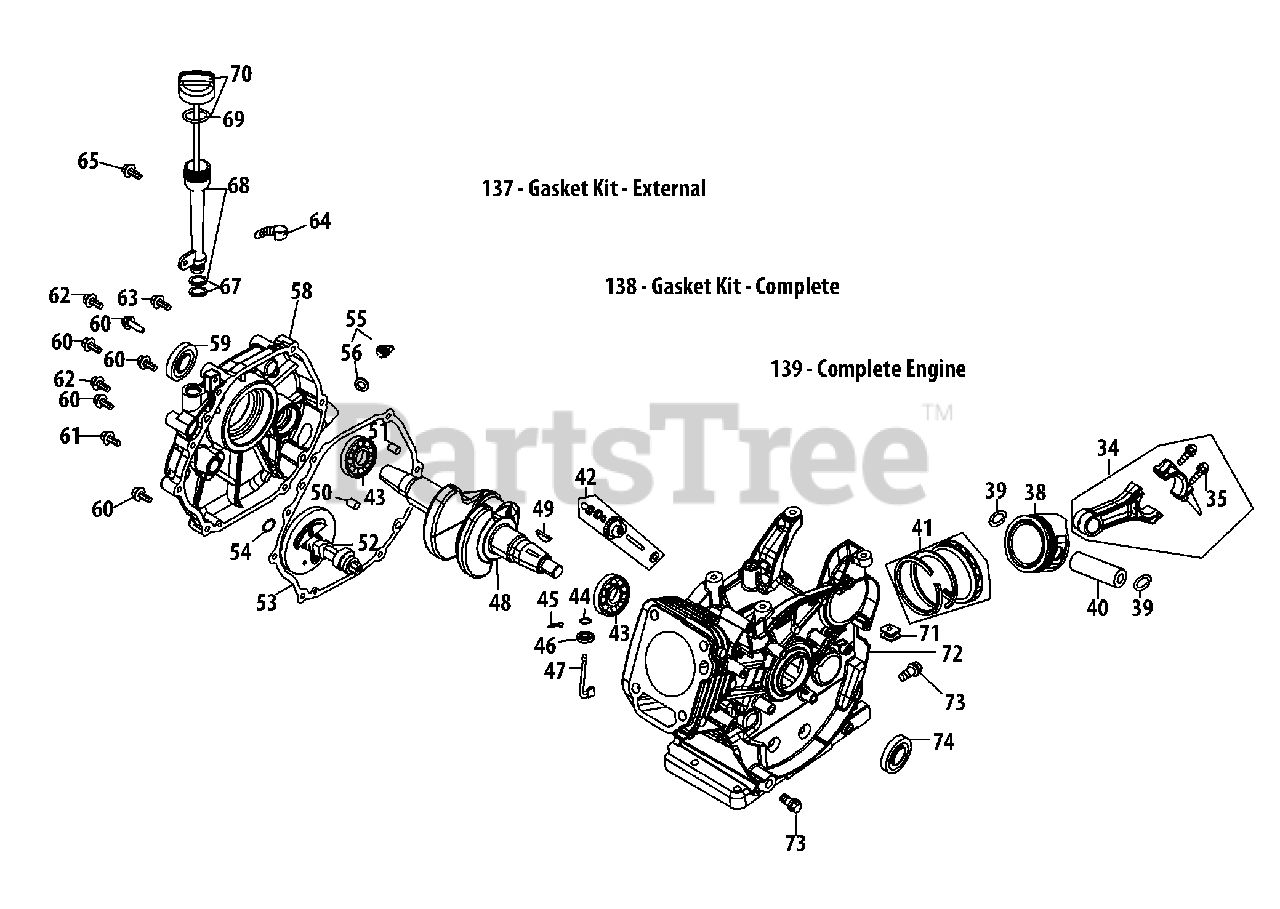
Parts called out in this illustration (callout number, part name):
34	Connecting Rod Assembly
35	Connecting Rod Bolt
39	Piston Pin Snap Ring
40	Piston Pin
41	Piston Ring Set
42	Governor Gear/Shaft Assembly
43	Radial Ball Bearing
44	Washer 8×20×0.8
45	Cotter Pin
46	Governor Seal
47	Governor Arm Shaft
48	Crankshaft Kit
49	Woodruff Key
50	Dowel Pin 9×12
51	Dowel Pin 7×14
52	Camshaft Assy.
53	Crankcase Cover Gasket
54	Washer 16×24×0.5
55	Oil Fill Plug Assembly
56	O-Ring 15.8×2.5
58	Crankcase Cover
58	Crankcase Cover Kit
59	Oil Seal, 30×46×8
60	Bolt M8×38
61	Bolt M8×45
62	Bolt M8×35
63	Bolt M6×16
64	Dipstick Clamp
65	Bolt M6×8
68	Oil Fill Tube Assembly
69	O-Ring, Dipstick
70	Disptick Assembly
71	Wire Clamp Rubber
72	Crankcase Service Kit
72	Shortblock Assembly
73	Oil Drain Plug
74	Oil Seal 30×46×8
137	Gasket Kit - External
138	Gasket Kit - Complete
139	Complete Engine
